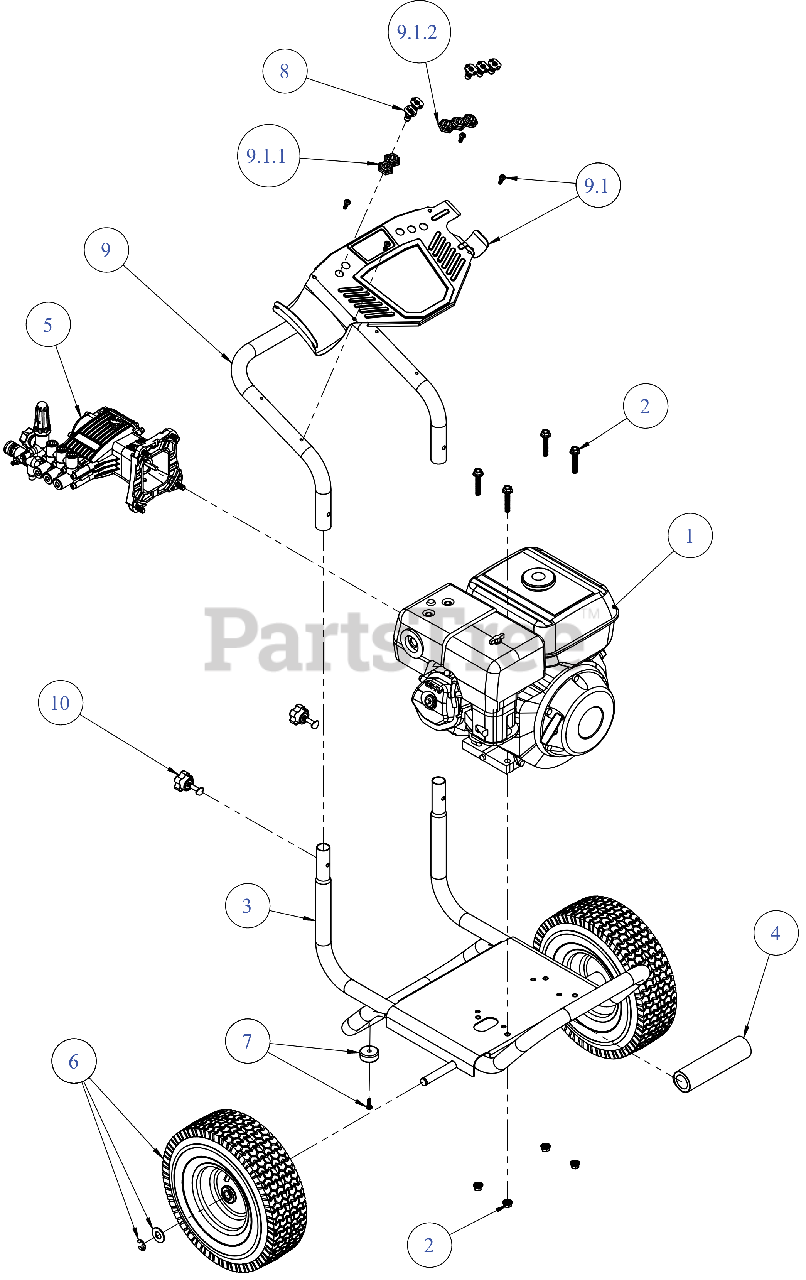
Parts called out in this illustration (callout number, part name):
1	ENGINE, SVC ASSY HONDA GX270 W/LABELS
2	ENGINE MOUNTING KIT
3	BASE ASSEMBLY-FRAME
4	GRIP-HANDLE
5	PUMP ASSEMBLY
6	13" WHEEL (BEIGE)
8	NOZZLE SET-5 PIECE
9	REAR HANDLE (W/LABEL CC 4033)
9.1	PNL-DASHBRD WABEL CC 4033 WASH
9.1.1	HOLDER-NOZZLE 2 PC
9.1.2	HOLDER-NOZZLE 3 PC
10	KNOB-HANDLE MTG
